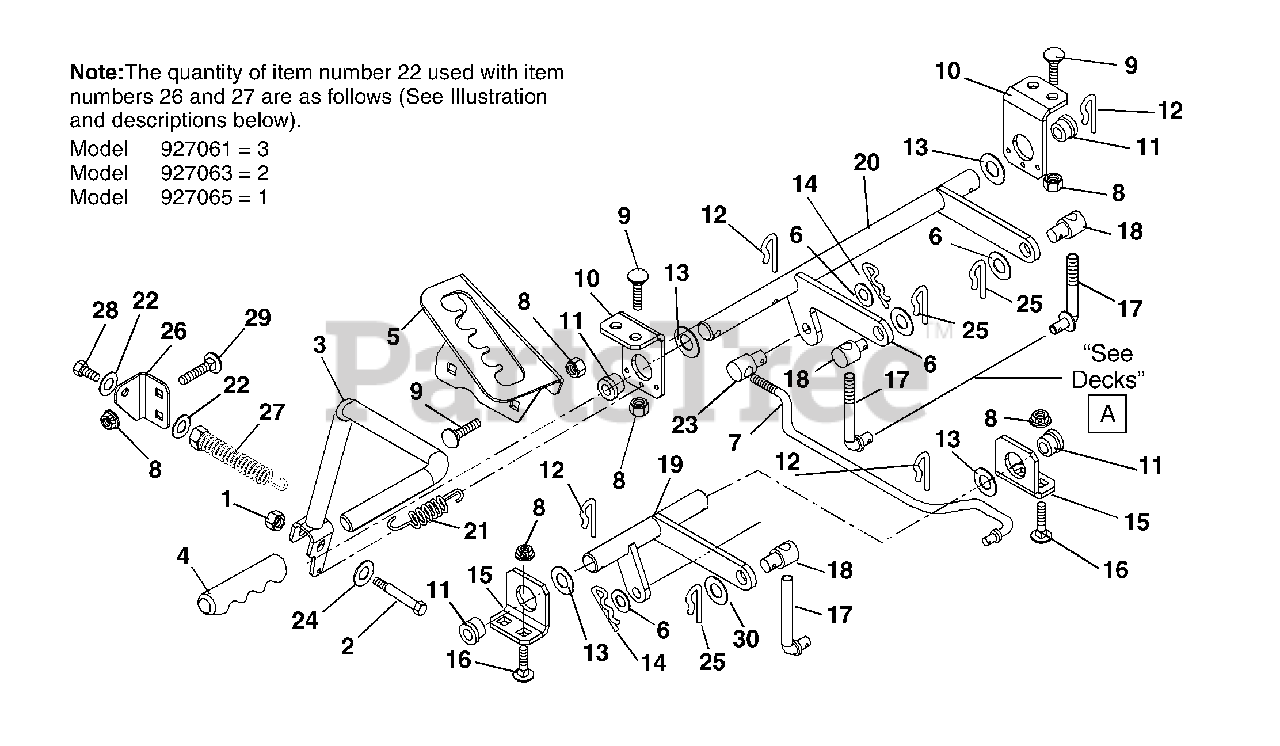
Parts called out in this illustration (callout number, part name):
1	NUT-LK-TOP-FLG .31-18 BLKZC
2	BOLT,SHLDR .38X1.25 .31-18 PLN
3	WLDM'T LIFT HANDLE
5	DETENT PLATE
6	WSHR-FL-STL.511X1.441X.125 YWZ
7	ROD, DECK LIFT
8	NUT-LK-TOP-FLG .38-16 BLKZC
9	BLT-RDHDSQNK .38-16X.75 G5BZ
10	BRACKET-HANGER
11	BSHG-FLG .750X1.000X.625X1.250
12	PIN, SPRING CLIP
13	WSHR-FL-STL .265X1.370X.179
14	PIN, HAIR, EXT - #16 YWZC
15	BRACKET-PIVOT
16	BLT-RDHDSQNK .38-16X1.00 G5BZ
17	LINK, LIFT
18	TRUNNION-.50
19	WMT, FRONT LIFT
20	WMT, REAR LIFT
21	SPRING, EXTENSION
22	WSHR,FLT .438X1.00X.160 ZCC
23	PIVOT, ROD
24	WSHR,FLT .438X1.00X.160 ZCC
25	CLIP, SPRING
26	BKT, SPRING ANCHOR
27	SG-TENS .195X1.147X5.50
28	@BLT-HEX .38-16X1.50 GR5 YWZC
29	BLT-RDHDSQNK .38-16X.75 G5BZ
30	@WSHR-FL-STL.563X1.38X.109YWZC
